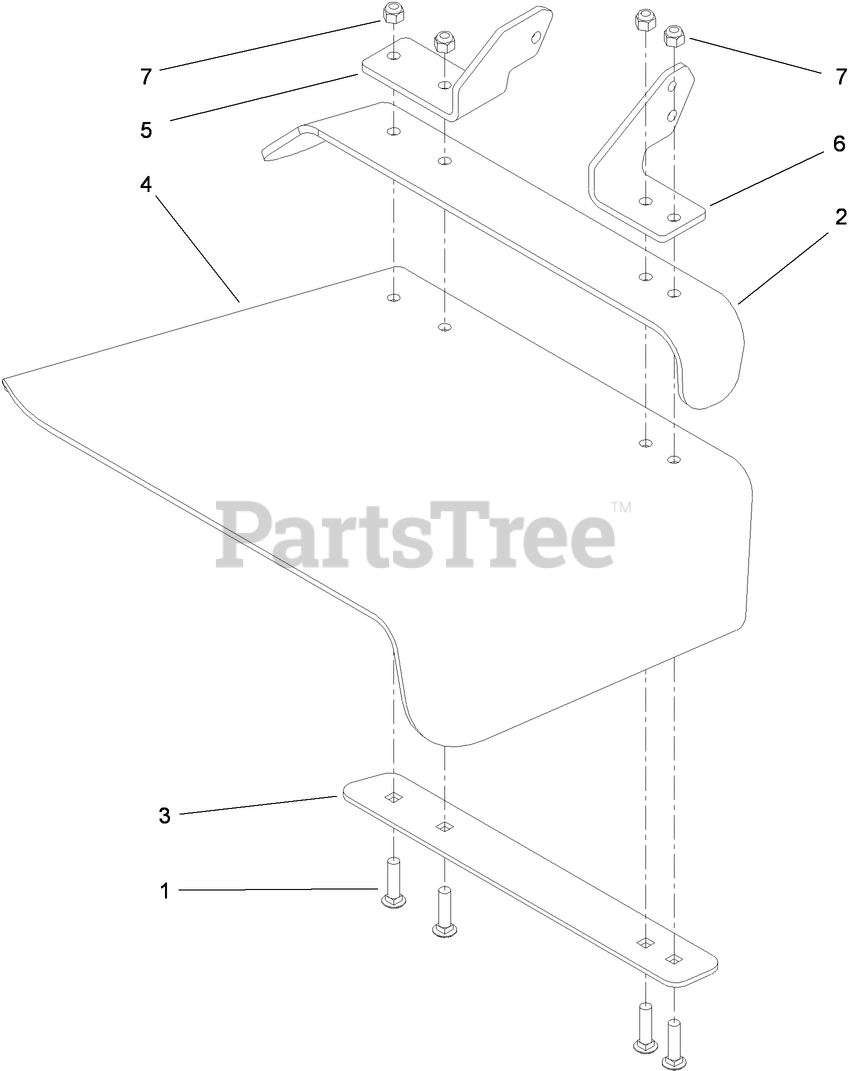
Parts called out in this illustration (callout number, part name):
1	SCREW-CARR
2	DEFLECTOR
3	STRAP-DISCHARGE
4	DEFLECTOR-RUBBER
5	PLATE-HINGE, REAR
6	PLATE-HINGE, FRONT
7	NUT-LOCK, NI
